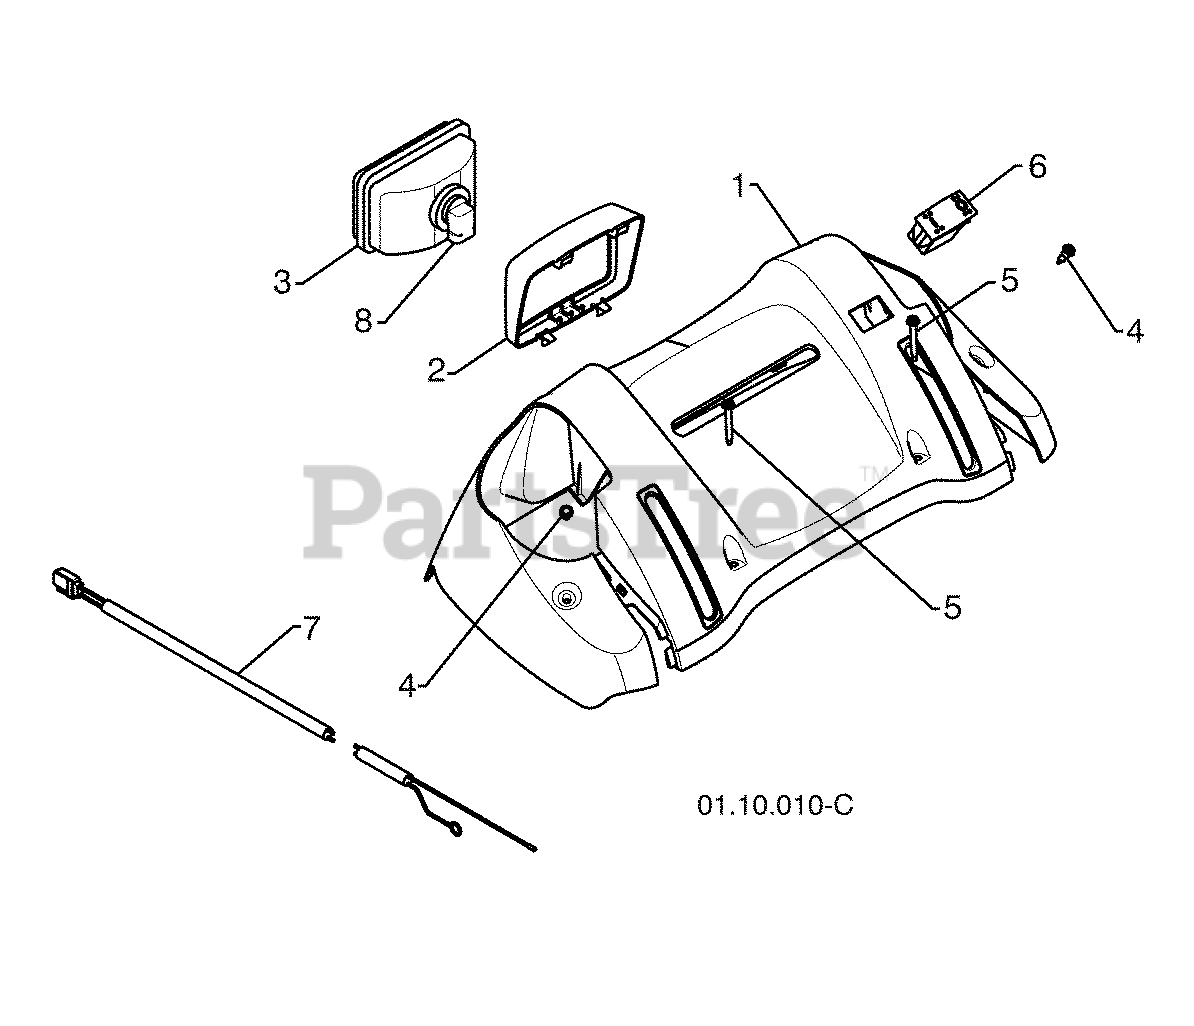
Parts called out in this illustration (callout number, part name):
1	CONSOLE PANEL GRAY
2	HEADLIGHT BEZEL GRAY
3	HALOGEN HEADLIGHT
4	SHOULDER SCREW 10-24 X .625
5	SCREW 10-24 X 1.25
6	GRIP SWITCH
7	WIRE HARNESS
